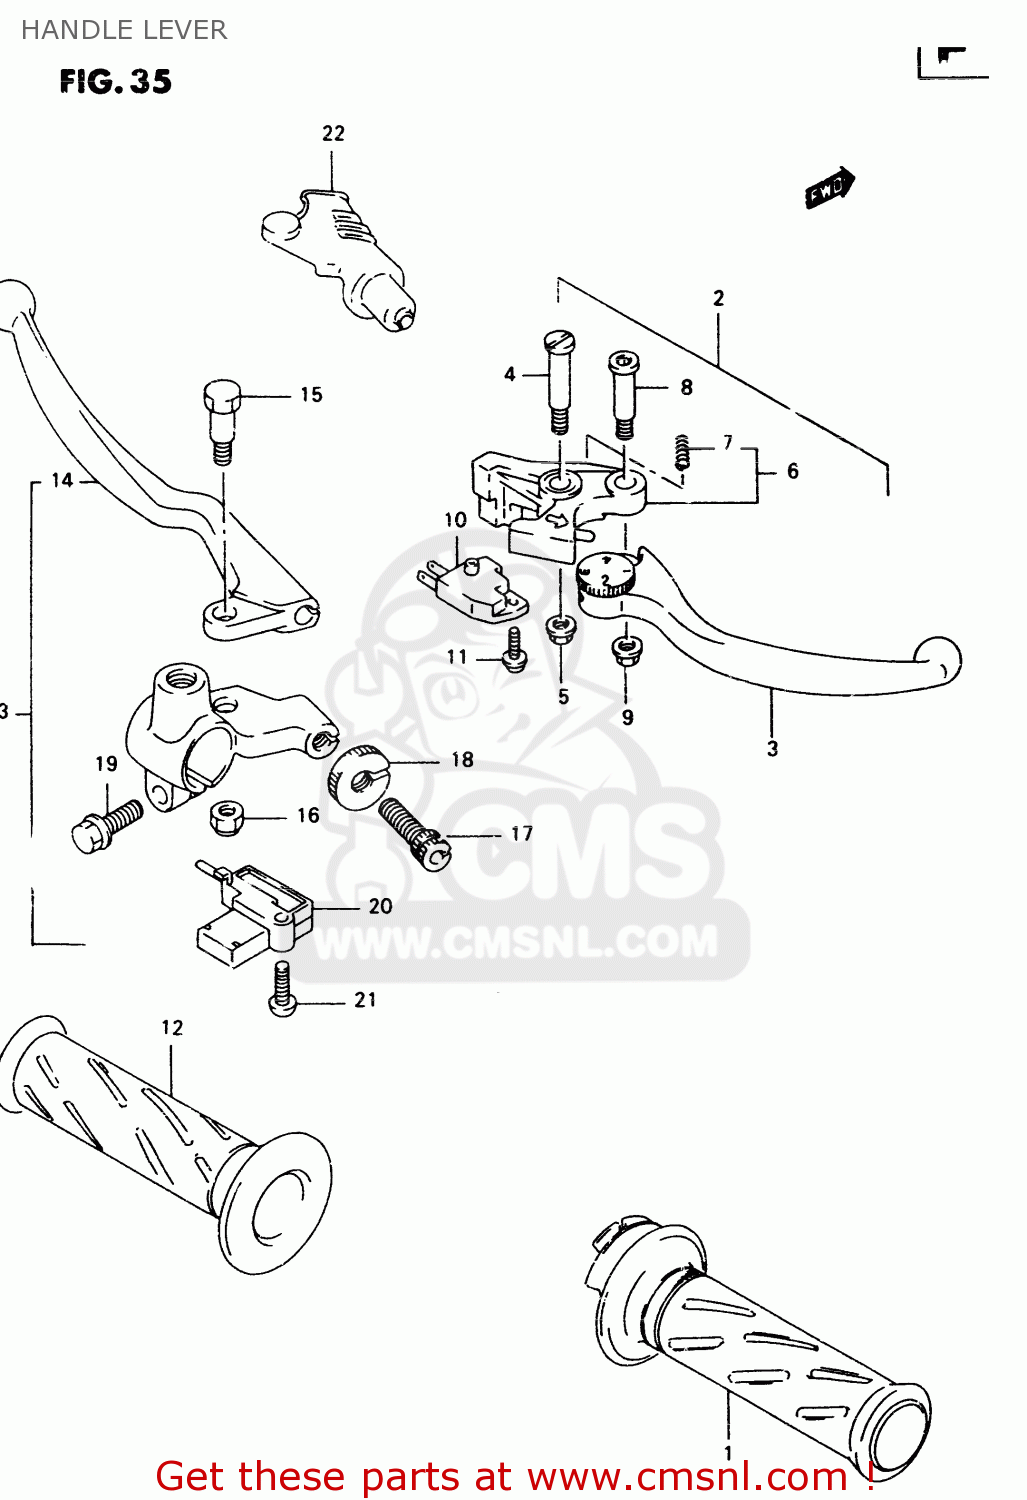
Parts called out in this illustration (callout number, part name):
1	GRIP,THROTTLE
2	LEVER ASSEMBLY,BRAKE
3	LEVER,ADJUST
4	BOLT,LEVER PIVOT
5	NUT
6	KNOCKER
7	SPRING
8	BOLT,LEVER
9	NUT
10	SWITCH ASSEMBLY,STOP
11	SCREW
12	GRIP,LEFT
13	LEVER ASSY,CLUTCH
14	LEVER,CLUTCH
15	BOLT,LEVER SET
16	NUT
17	ADJUSTER,WIRE
18	NUT,LOCK
19	SCREW
20	SWITCH,CLUTCH
21	SCREW
22	COVER,CLUTCH LEVER
